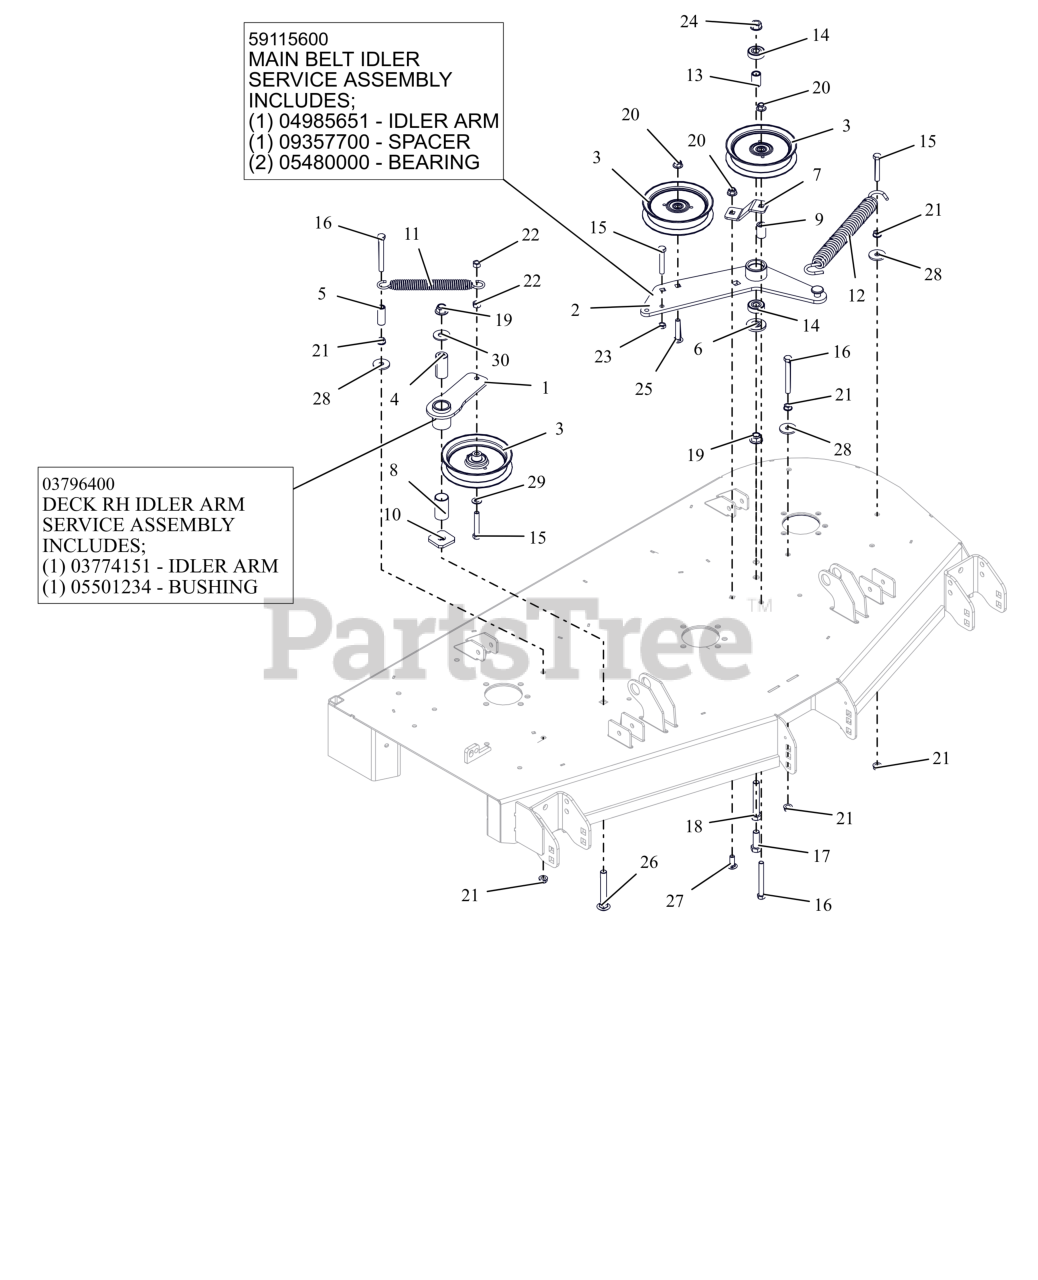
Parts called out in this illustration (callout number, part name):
1	WMT, IDLER ARM - BLACK
1	ASM, IDLER ARM (DECK)
2	DECK PTO IDLER ARM WLDMT - BLK
2	ASSEMBLY, MAIN BELT IDLER
3	IDLER, FLAT 5.00"
4	BSHG, SPCR .502X.997X2.03 PM
5	SPACER, .375IDX.625ODX1.66 PM
6	SPACER, IDLER ARM
7	PTO FIXED IDLER MTG BRKT-ORG
8	BSHG, 1.00X1.125X1.937
9	BUSHING, SLV .380X.750X1.190
10	WSHR-FLT .640X1.75X.250
11	SPRING, EXTENSION
12	SPRING, EXTENSION
13	SPACER .510 X .75 X 1.1485
14	BRG-BALL .500X1.38X.437
15	BLT,HEX .38-16X2.25 G5 ZCC
16	BLT, HEX .38-16X3.25 G5 ZCC
17	BLT,HEX .50-13X1.50 G5 ZCC
18	BLT,HEX .50-13X3.25 G5 ZCC
19	NUT,NYL-FLG .50-13 GF ZCC
20	NUT,NYL-FLG .38-16 GF ZCC
21	NUT, SPNLK-FLG .38-16 G5 ZCC
22	NUT-LK-CTR .38-16 ZC120
23	NUT-JAM .375-16 G2 ZCC
24	NUT-LK-CTR-FLG .500-13 GG ZCC
25	BLT,RHSSN.375-16X2.00 G5 ZCC
26	BLT, RHSN .50-13X3.50 G5 ZCC
27	BLT,RHSSN .38-16X1.00 G5 ZCC
28	WSHR,FLT .406X1.375X.135 ZCC
29	WSHR,FLT .406X.812X.065 ZCC
30	WSHR,FLT .563X1.375X.109 ZCC
